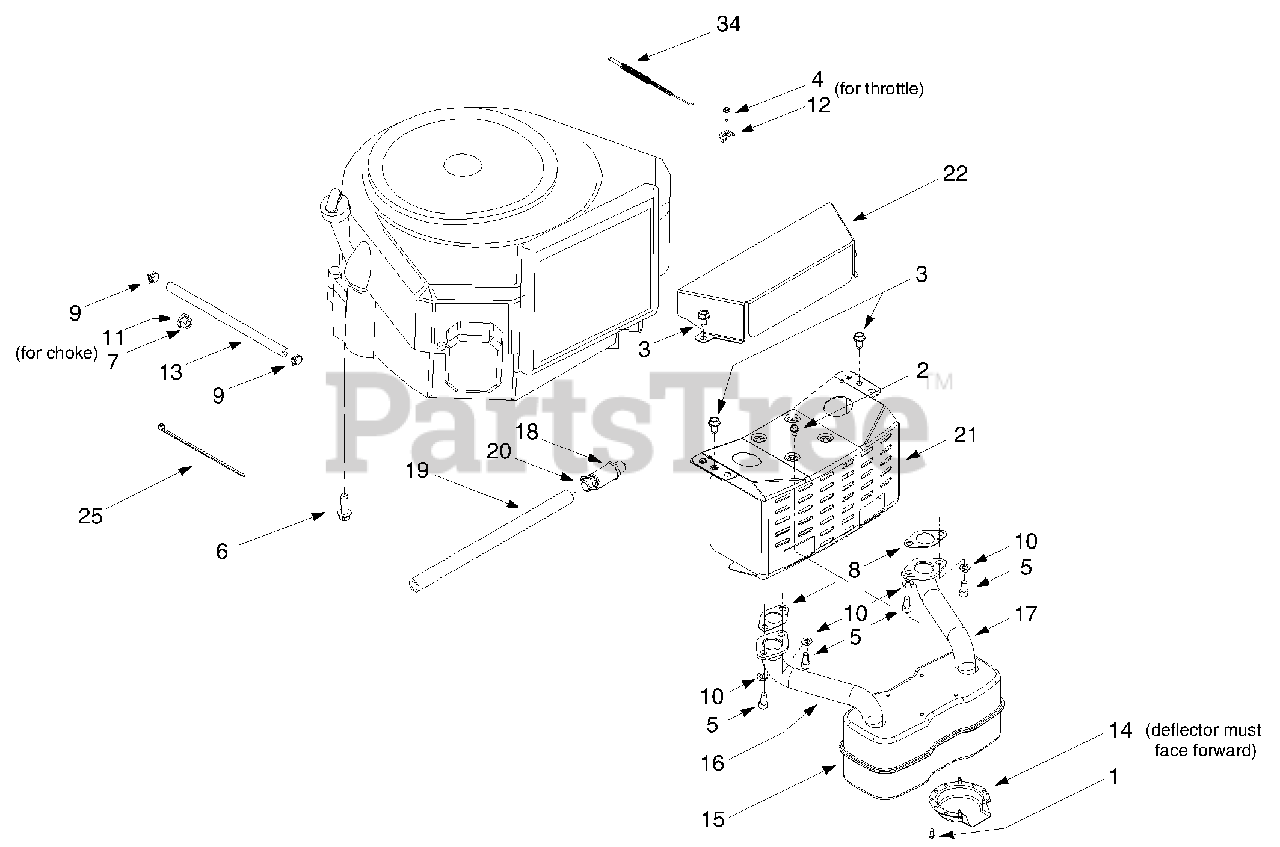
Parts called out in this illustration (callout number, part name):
1	Self Tapping Screw, #8-32 x .375
2	Self Tapping Screw, 1/4-20 x .5
3	Self Tapping Screw, 5/16-18 x .625
4	Screw, #10-32 x .625
5	Socket Cap Screw, 5/16-18 x .625
6	Self Tapping Screw, 3/8-16 x 1.25
7	Hex Nut, 3/8-16
8	Exhaust Gasket (Vanguard Twin) 1800
9	Hose Clamp
10	Lock Washer, 5/16
11	Lock Washer, 3/8 x .682 x .036
12	Casing Clamp
13	Fuel Line Hose, 14 inches
14	Muffler Deflector
15	Muffler, Twin Inlet
16	RH Exhaust Pipe (Vanguard Twin) 1800
17	LH Exhaust Pipe (Vanguard Twin) 1800
18	Oil Drain Valve
19	Oil Drain Hose
20	Oil Drain Cap
22	Engine Heat Shield
25	Cable Tie
34	Throttle Cable (Vanguard Twin) 1800
